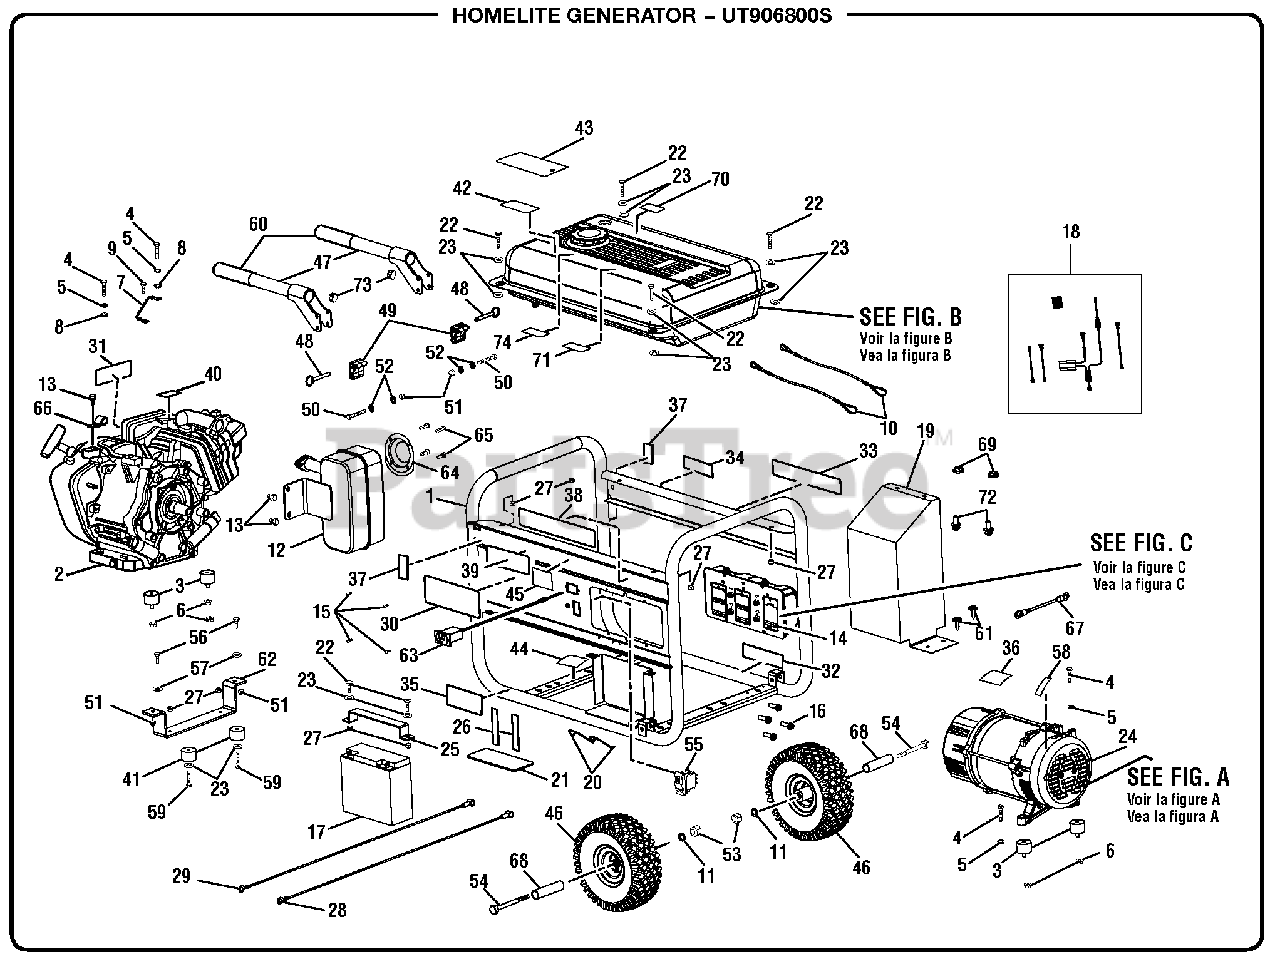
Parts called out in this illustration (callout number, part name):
1	Carrier Assembly
4	Bolt (5/16-18 x 1-1/2 in., Hex Hd.)
5	Lock Washer (5/16 in.)
6	Flange Nut (5/16-18, Hex Hd.)
7	Ground Wire Assembly
8	Star Washer (5/16 in.)
9	Bolt (5/16-18 x 3/4 in., Hex Hd.)
10	Lanyard (3/16 in.)
11	Washer (3/8 in)
13	Bolt (5/16-24 x 5/8 in.)
14	Control Panel Assembly
15	Screw (6-20 x 3/8 in.)
16	Bolt (3/8-16 x1.25 in.)
17	Battery
18	Wire Harness
19	Heat Shield
20	Cord Retainer
21	Battery Box Gasket
22	Bolt (1/4-20 x 1 in., Hex Hd.)
23	Washer (1/4 in.)
24	Generator Head w/AVR
25	Battery Hold Down Bracket
26	Gasket (Battery Hold Down Bracket)
27	Lock Nut (1/4-20)
28	Battery Cable (Red)
29	Battery Cable (Black)
30	Logo Label
31	Electric Start Label
32	Hot Surface Label
33	Danger Label
34	Fire Danger Label
35	Engine Lubricant Label
36	Data Plate Label
37	Locking Pin Label
38	Yamaha Label
39	Electric Start Label
40	Choke Label
41	Rubber Feet
42	CPSC Label
43	Danger Hang Tag
44	Inquires Label
45	Combustion Warning Label
47	Handle Assembly
48	Release Pin (5/16 x 2 in.)
49	Handle Bracket Spacer
50	Bolt (5/16-18 x 1-1/2 in., Hex Hd.)
51	Lock Nut (5/16)
52	Washer (5/16 in.)
53	Lock Nut (3/18-16 )
55	Start Switch w/Lock
56	Bolt (5/16-18 x 1 in., Hex Hd.)
57	Flat Washer (5/16 in.)
58	Ground Label Icon
59	Bolt (1/4-20 x 1-1/2 in., Hex Hd.)
60	Handle Grip
61	Screw (8 x .75 in.)
62	Front Foot
63	Voltage Meter
64	Spark Arrestor
65	Screw (8-32 x 3/8 in., Pan Hd.)
66	J-Clamp (1/2 in.)
67	Bonding Wire
69	Flange Nut (M6)
70	E85 Label
71	Mexico Support Label
72	Bolt (M6 x 12 mm)
74	Fire Distance Label
